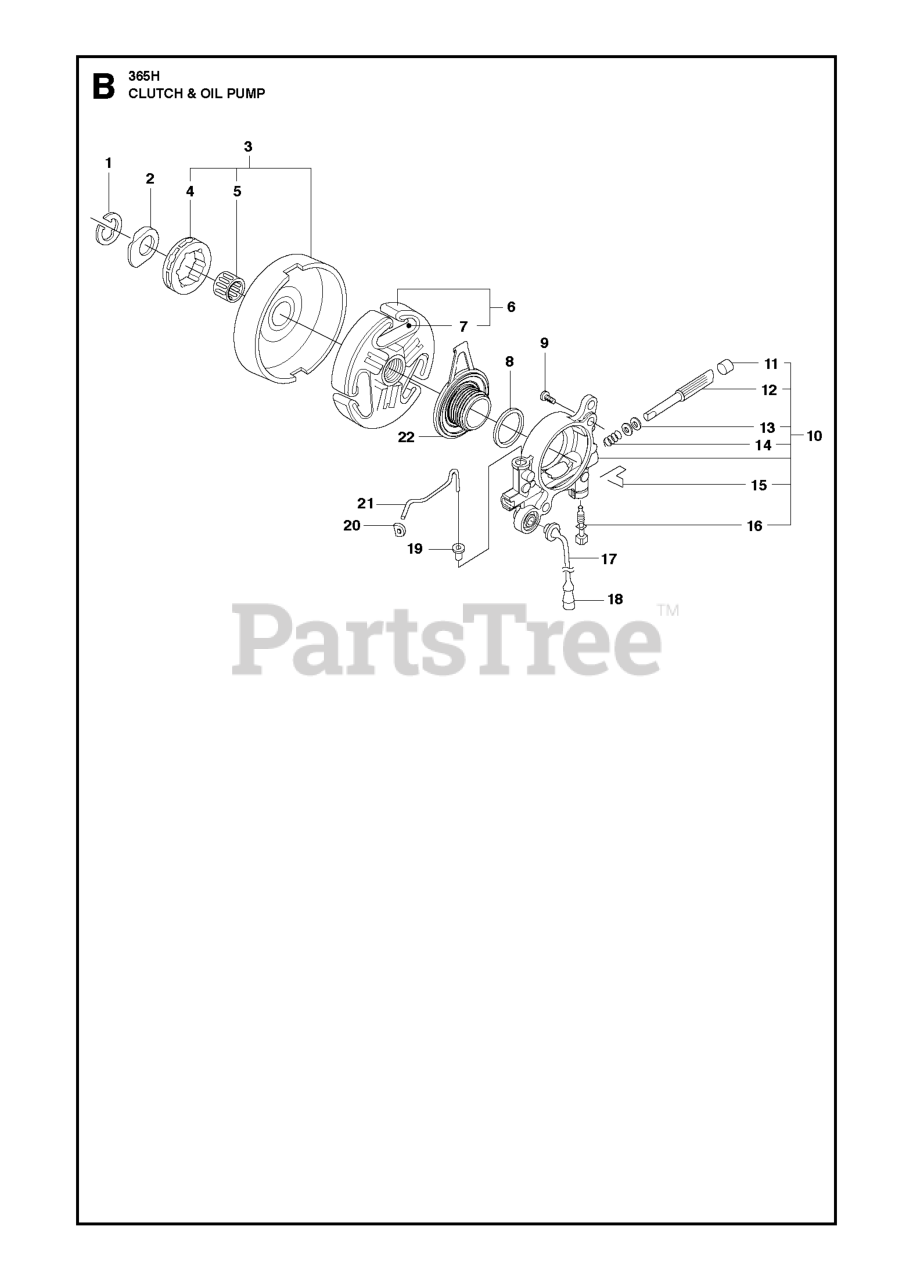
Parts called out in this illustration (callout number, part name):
1	RETAINING RING
3	CLUTCH DRUM ASSY
4	68210 RIMSPROCKET
4	22273 Sprocket 3/8"x8T
5	CLUTCH DRUM BEARING
6	CLUTCH ASSY M14X1.25-6H
9	SCREW MC6S 5X16
10	OIL PUMP
12	PUMP PISTON
13	WASHER 6.1X9
15	SPRING CLIP
18	OIL SCREEN
22	PUMP PINION
